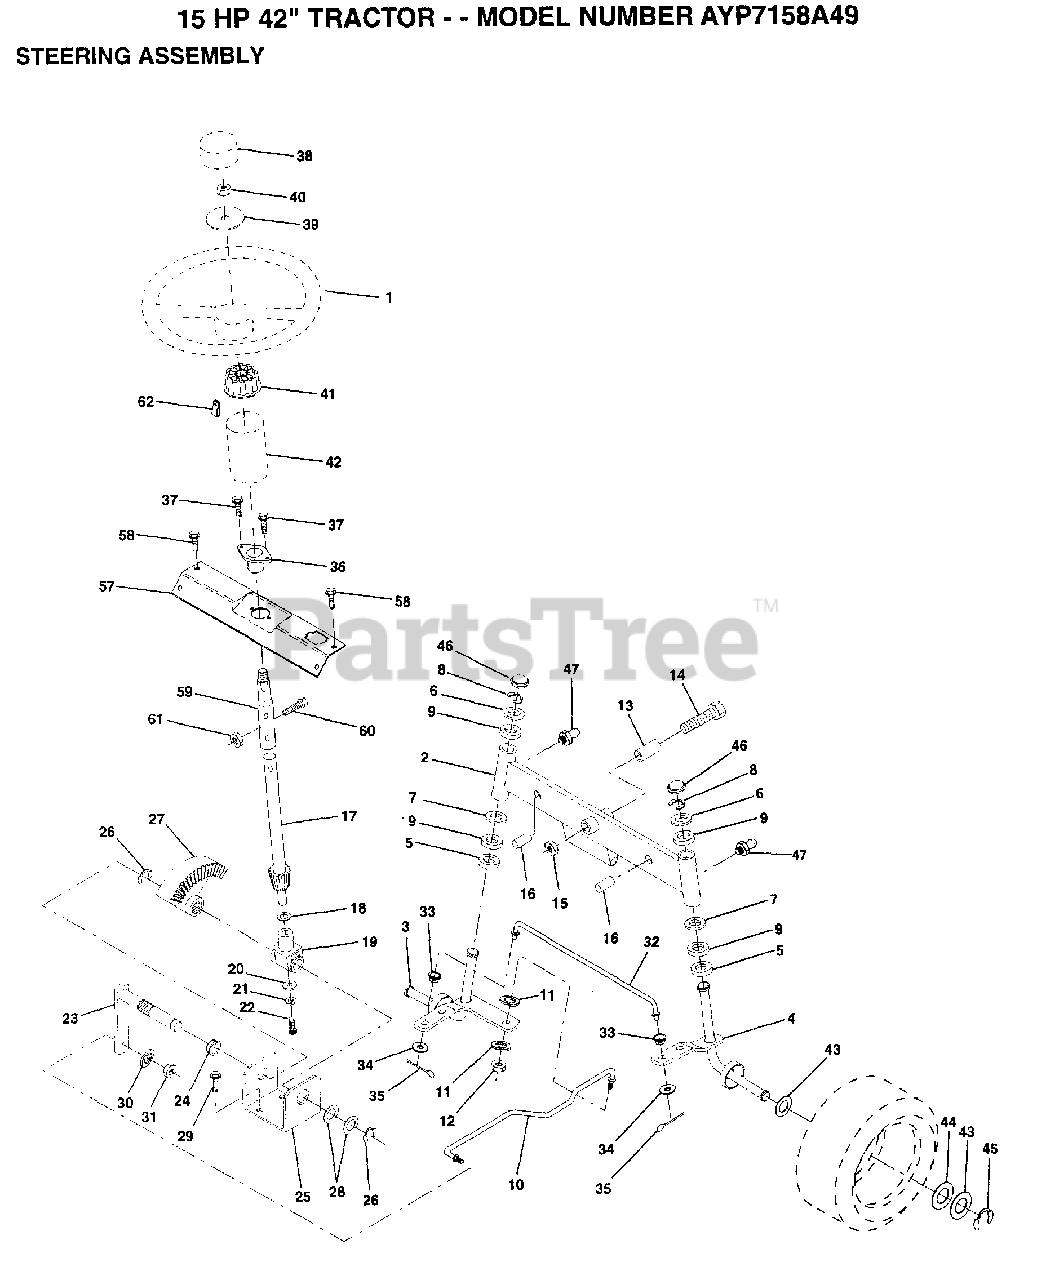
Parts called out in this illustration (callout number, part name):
1	WHEEL STR AYP BLK
2	AXLE ASM FRONT
3	SPINDLE LH
4	SPINDLE RH
5	WASHER .T
6	WASHER
7	WASHER
8	RING
9	COL. SRTG. BEAR.
11	LOCKWASHER
13	BEARING
14	BOLT HEX 5/8-11
15	"NUT-LOC,FLANGE LT"
16	AXLE PIN
17	SHAFT ASM STEERIN
18	THRUST WASHER
19	SUPPORT.SHAFT
21	LOCKWASHER
22	"SCREW,SPECIAL"
24	NYLINER T
25	"BRKT,STEERING"
26	RING
27	GEAR SECTOR
28	WASHER .T
29	SCREW
30	LOCKWASHER
32	TIE ROD
33	BUSHING.DRAGLINK
34	WASHER
35	COTTER PIN
38	CAP STEER AYP
39	WASHER T
40	GRIPCO NUT
41	ADAPTER-WHEEL LT
42	BOOT SHAFT STEER
43	WASHER
44	WASHER
45	RING
46	CAP
47	ZERK M
57	SUPPORT SHAFT STR
58	SCREW HEX CRT
59	SHAFT EXT STEER
60	BOLT
61	NUT
62	CLIP TIMMERMAN
